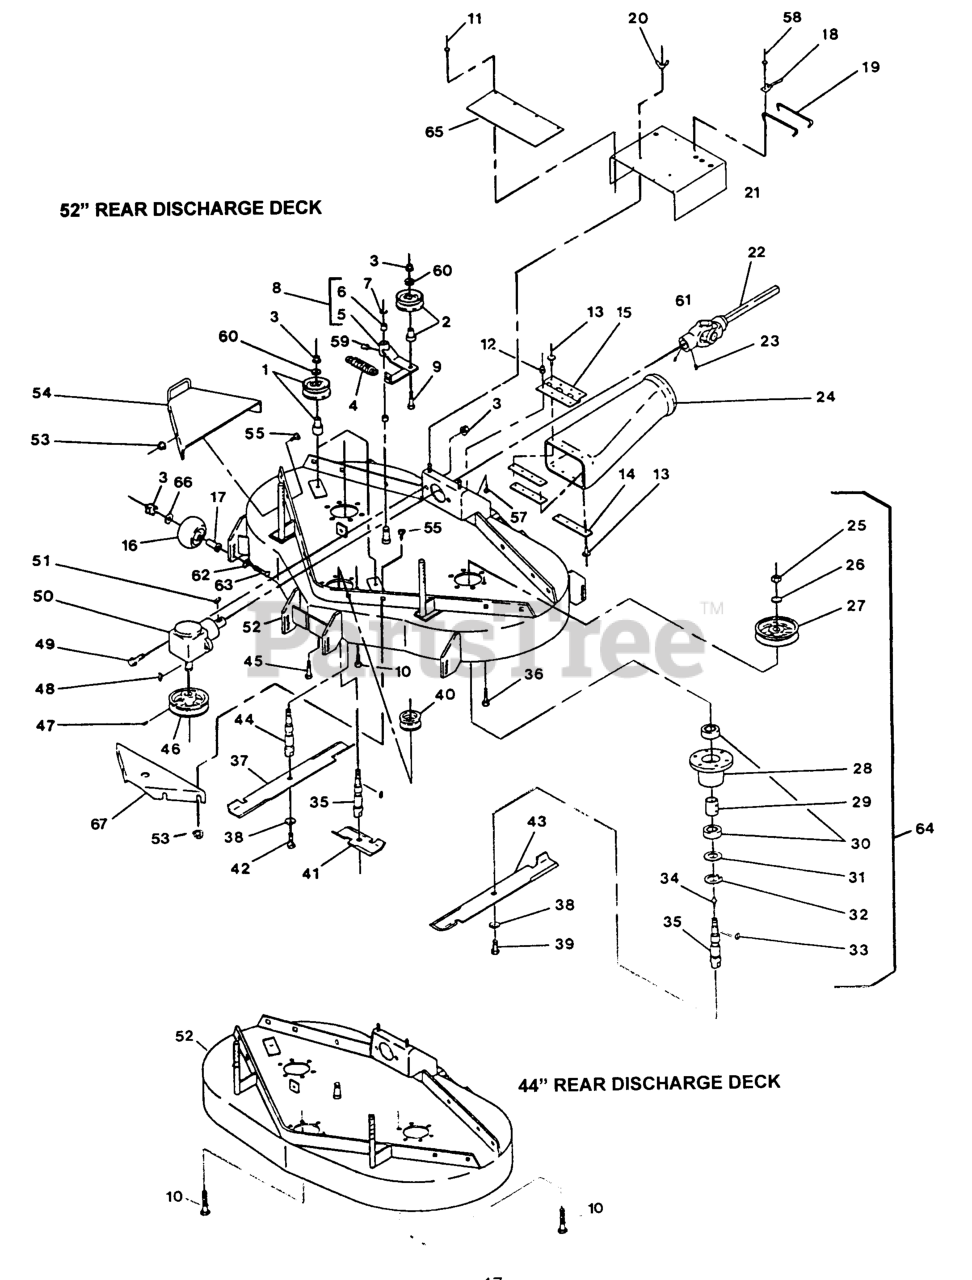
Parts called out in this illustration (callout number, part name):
1	KIT,IDLER & BUSHING
4	SPRING-IDLER, DECK
6	SLEEVE-BEARING
11	RIVET-POP
16	ROLLER-SCALP, ANTI
17	BUSHING-ROLLER
18	CLIP-DECK, HOLD UP ROD
20	WINGNUT-NYLOCK
22	PTO SHAFT,SHAFT HALF PNT
26	WASHER-SPRING
27	SHEAVE,BLADE DRIVE
29	SPACER,BEARING
31	SEAL,MECHANICAL DUST
32	RING,SNAP WLDS N5000-244
36	SCRW,TPTTE HH
38	WASHER-SPRING
42	SCREW-CAP,HH
46	SHEAVE,5.45 O.D.
47	SCREW-SET
50	GEARBOX, PEERLESS
57	BOLT-CARR
58	Pop Rivet, Steel 3/16 X .250
65	SHIELD,PTO GUARD
